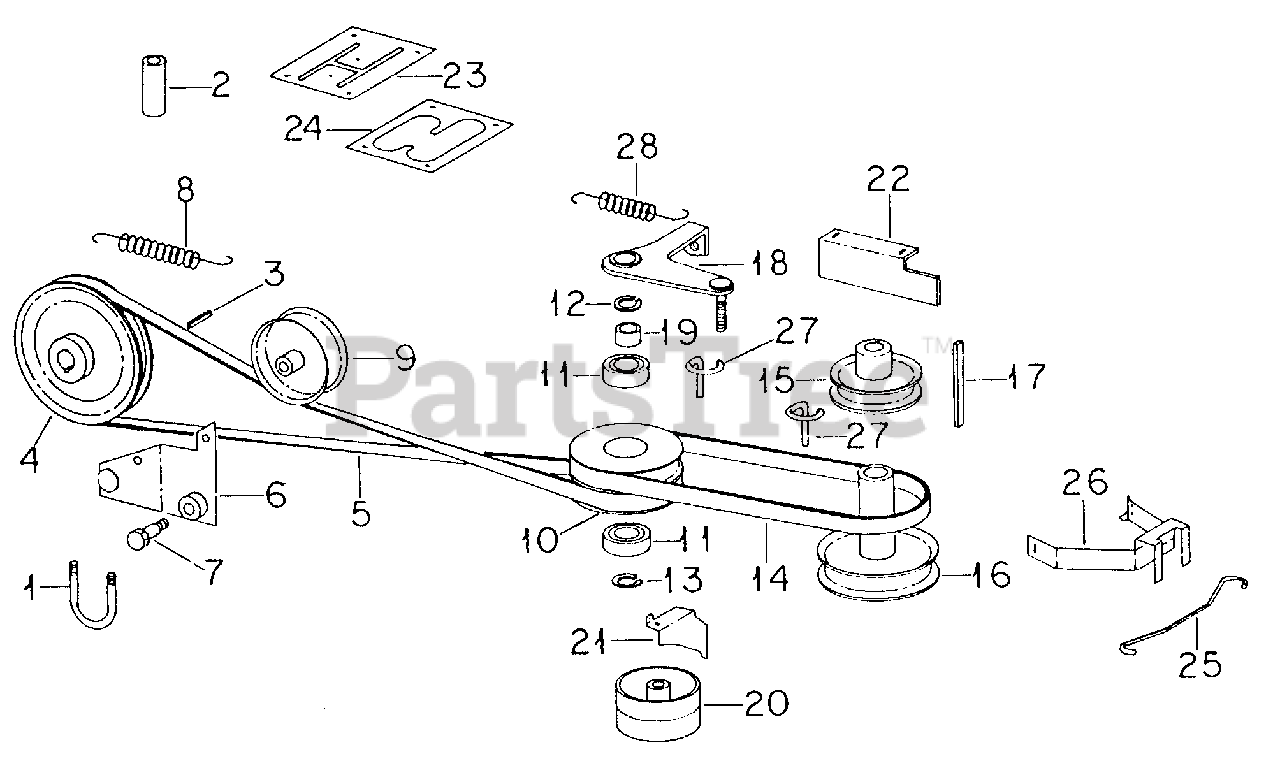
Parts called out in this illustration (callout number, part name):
2	Spacer, Transaxle Mounting
3	Key, 3/16 X 3/4 Woodruff 3 No. 9
4	Pulley, Transaxle
5	Belt, Mower & Final Drive
6	Arm Assy, Belt Tensioning
7	Bolt, IPTO Shoulder
8	Spring, Extension
9	Pulley, Final Drive Idler
10	Pulley, Intermediate Drive
11	Bearing, Intermediate Pulley
12	Ring, External Retaining
13	Ring, Internal Retaining
14	Belt, Clutching
15	Pulley, Engine Drive
16	Pulley, Mower Drive, 4-5/8 inch diameter
17	Key, 1/4 X 2-3/4 Sq Parallel
18	Bushing Assy, Clutch
19	Bushing
20	Pulley, Mower Shifter Idler
21	Guide, Belt
22	Guide, Belt
23	Cover, Gear Shift Hole
24	Plate, Gear Shift Hole
25	Support, Belt Guide
26	Guide, Engine Belt
27	Guide, Transaxle Belt
28	Spring, Extension
